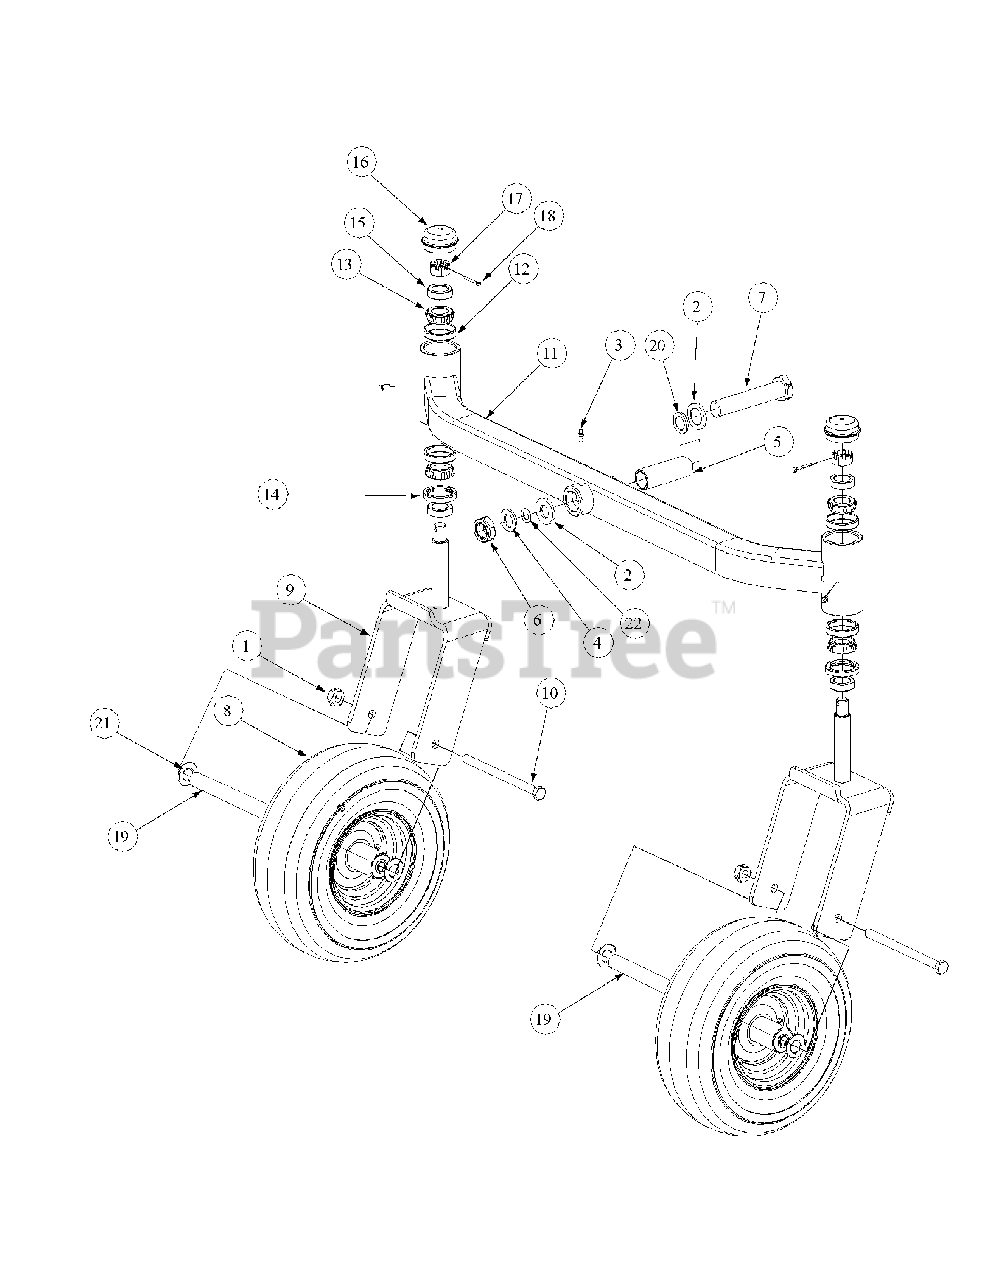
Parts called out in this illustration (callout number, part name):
1	Nut, 1/2-20, Center Lock
2	Bell Washer, 1.25 ID
3	Grease Fitting
4	Special Washer
5	Spacer, 1.005 ID x 1.25 OD x 3.6
6	Nut, Jam, 1.0-14, Insert Lock
7	Hex Cap Screw, 1-14 x 5.0
8	Wheel Assembly, 13 x 6.50 x 6, White, includes:
9	Yoke, Caster Wheel
10	HHCS, 1/2-20, 7.50
11	Front Axle Assembly
12	Cup Bearing
13	Bearing Cone
14	Seal
15	Ring Seal
16	Grease Cap, 1.986 OD
17	Slotted Nut, 3/4-16
18	Cotter Pin, 5/32, 1.25
19	Wheel Spacer
20	Flat Washer, 1.25 ID
21	Spacer, .812 ID x .218 LG
22	Retainer Extension, Self Locking
